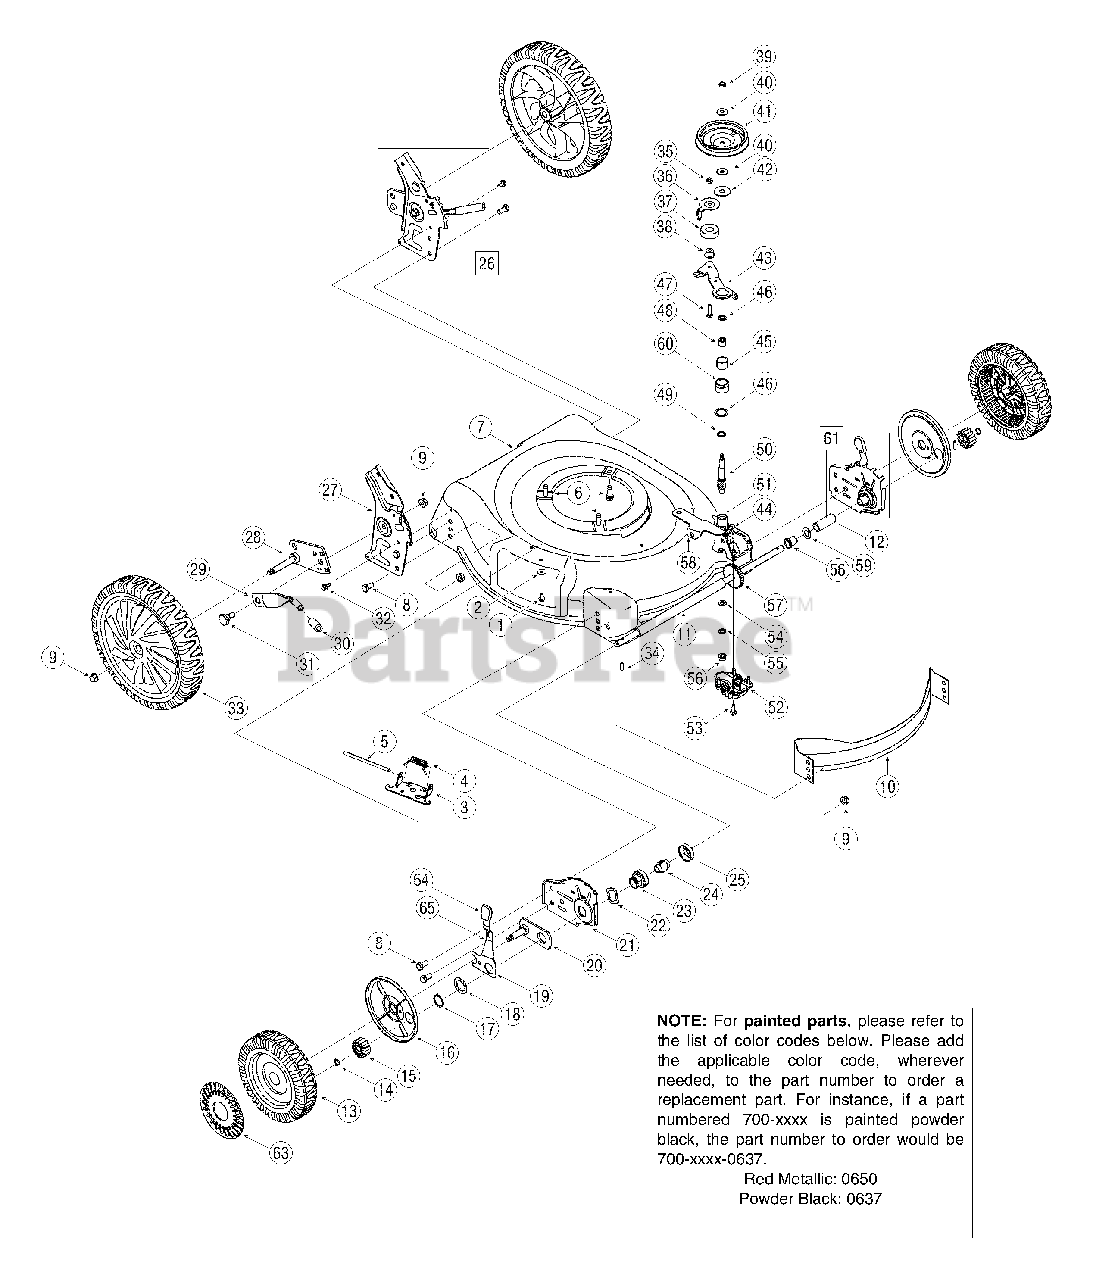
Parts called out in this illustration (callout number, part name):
1	TT Screw 1/4-20 x 0.5
2	Bell Washer.265 x 0.75
3	Deflector Chute Adapter
4	Torsion Spring
5	Hinge Pin
6	Self-Tapping Sems Screw
9	Hex Nut 3/8-16
10	Front Baffle
11	Sleeve Spacer 10.1" Lg.
12	Slev. Spacer 2.1" Lg.
13	Wheel 8 x 2.125 Black Zag Gear
15	Gear 14T RH FWD
16	Wheel Dust Cap
19	Lever Assembly RH
20	Pivot Plate Assembly
23	Bearing Support
24	Bearing Sleeve
25	Bearing Retainer
26	Handle Bracket Assembly - LH
27	Handle Bracket - RH
28	Pivot Bar RH
29	Height Adjustment Lever
31	Shoulder Scr.500 Dia. x.434
32	Tt Screw 1/4-20 x.625"
33	Wheel, 12 x 2.125 Zag Gray IDL
34	Dowel Pin
37	Ball Bearing
38	Flange Bearing
39	Hex Jam Nut 5/16-24
40	Bell Washer.325 x.930 x.45
41	Pulley, 3.82 x.313 x.68
42	Flat Washer.422 x 1.38 x.060
43	Front Idler Assembly
44	Extension Spring
45	Bearing Sleeve
46	Fl-Wash.865 x 1.145 x.030
47	Hex Screw 1/4-28 x 1.0
48	Needle Bearing.438 x.625 x.500
49	Flat Washer.504 x.700 x.030
50	Pinion Shaft
51	Upper Housing
52	Lower Housing
53	Hex Screw w/Washer 1/4-20 x.750
54	Thrust Washer.375 x.070 x.030
55	Thrust Washer.388 x.625 x.062
56	Flange Bearing
58	Idler Cable Bracket Assembly
59	Oil Seal
61	Height Adjustment Assembly LH
62	Transmission Assembly Comp.
63	Radial Spoke Hubcap
64	Adjustment Knob
65	Front Lever RH
